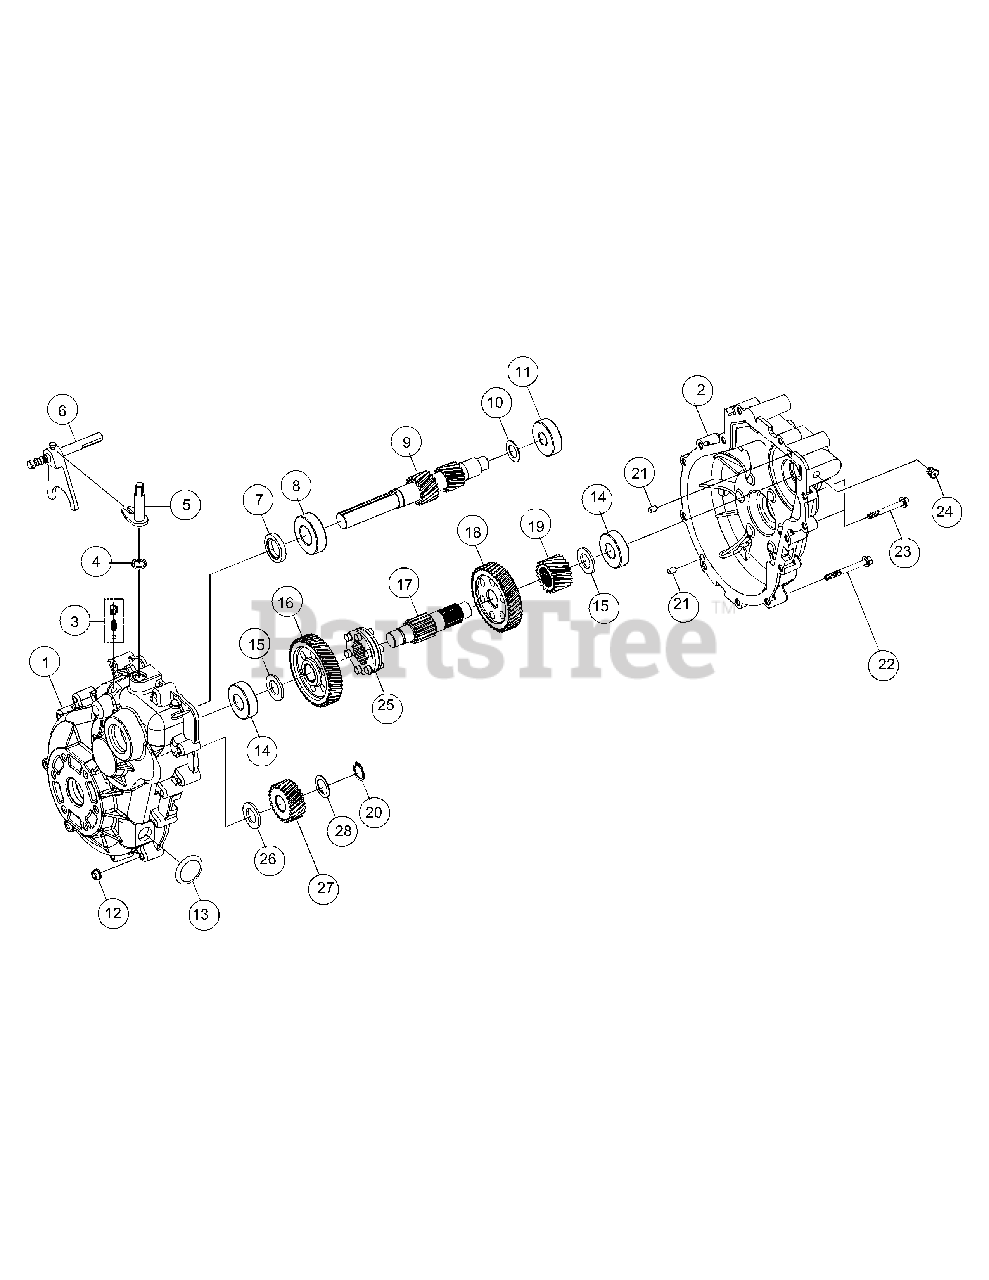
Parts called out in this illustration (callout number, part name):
1	Housing, Axle, w/Idler Shaft
2	Housing, Axle, Finished
3	Kit, Detent
5	Assembly, Actuator
6	Assembly, Shift Rod
8	Bearing, Ball
9	Shaft, Input
10	Kit, Shim
11	Bearing, Ball
13	Plug, Rubber
14	Bearing, Ball
15	Spacer, Flat
16	Gear Assembly, Forward
17	Shaft, Intermediate
18	Gear Assembly, Reverse
19	Gear, Helical (Pinion)
20	Ring Retaining
22	Screw, Flange Head
23	Screw, Flange Head
25	Gear, Clutch
26	Washer, Thrust
27	Gear, Assembly, Idler
28	Washer, Thrust
